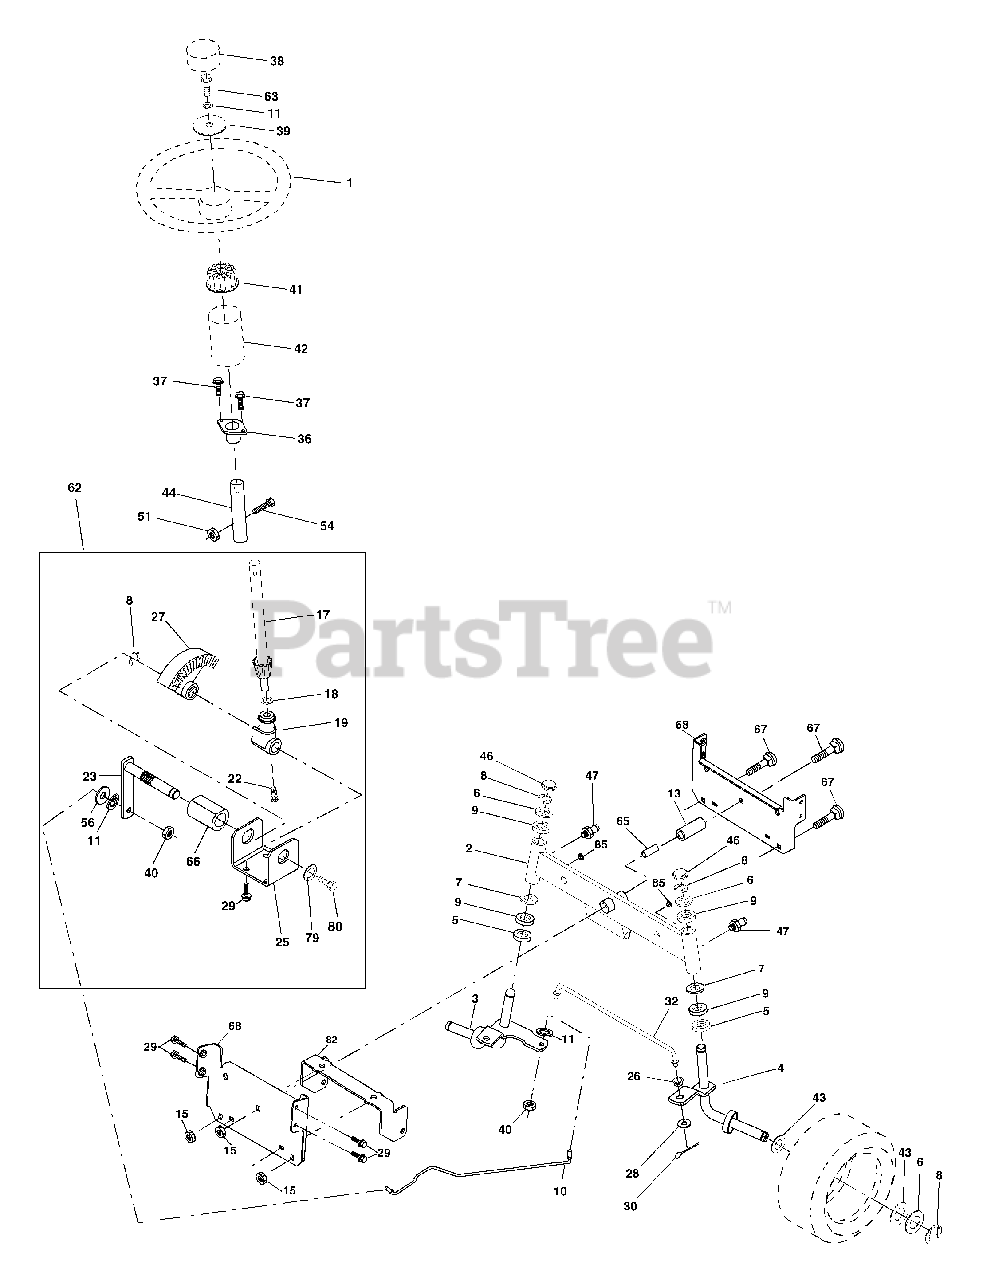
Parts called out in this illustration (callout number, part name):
1	Wheel Steering Auto Black
2	Axle Asm Front
3	Spindle Asm Lh
4	Spindle Asm Rh
5	Bearing Race Thrust Harden
6	Washer 25/32 X 1 5/8 X 16ga
7	Washer 27/32 X 1 1/4 X 16 Ga
8	Ring Klip #t5304-75
9	Bearing Col Strg Blk
10	Link Drag
11	Lockwasher
13	Spacer Bearing Axle Front
15	Nut Hex Flange Lock
17	Shaft Asm Strg 5/8 X 15 19 Lt
18	Washer Thrust 515x 750x 033
19	Support Shaft
22	Screw Hex Wsh Hd Torx
23	Shaft Asm Pittman
25	Bracket Steering
26	Bushing Rod Tie Blk Lt
27	Gear Sector
28	Washer 13/32 X 7/8 X 16ga
29	Screw 3/8-16x3/4
30	Pin
32	Rod Tie Wire Form 19 75 Mech
36	Bushing Strg 5/8 Id Dash
37	Screw TT #10-32 x 5 x 3/8 Flange
38	Insert Cap Strg
39	Washer 13/32 X 2-3/8 X12 Ga
40	Locknut Center
41	Adaptor Wheel Strg 640/ 635id
42	Boot Dash Steering
43	Washer 25/32 X 1 1/4 X 16 Ga
44	Extension Steering Non-Adjust
46	Cap Spindle Fr Top Blk
47	Fitting Grease
51	Nut Lock Hex W/Ins.
54	Bolt Fin Hex 5/16-18 Unc P
56	Washer 13/32 x 3/4 x 10 Ga.
62	Kit Steering Assembly Service
63	Bolt Fin Hex 3/8-16unc x Gr. 5
65	Spacer Axle
66	Bearing Arm Pittman
67	Bolt Rdhd Sq 3/8-16 Unc x 2-1/4
68	Brace Axle
79	Washer 13/32 x 1-1/4 x 12 Ga.
80	Bolt Hex Nylon 3/8-16 x 3/4
82	Bracket Susp Chassis Front
85	Fastner Christmas Tree
